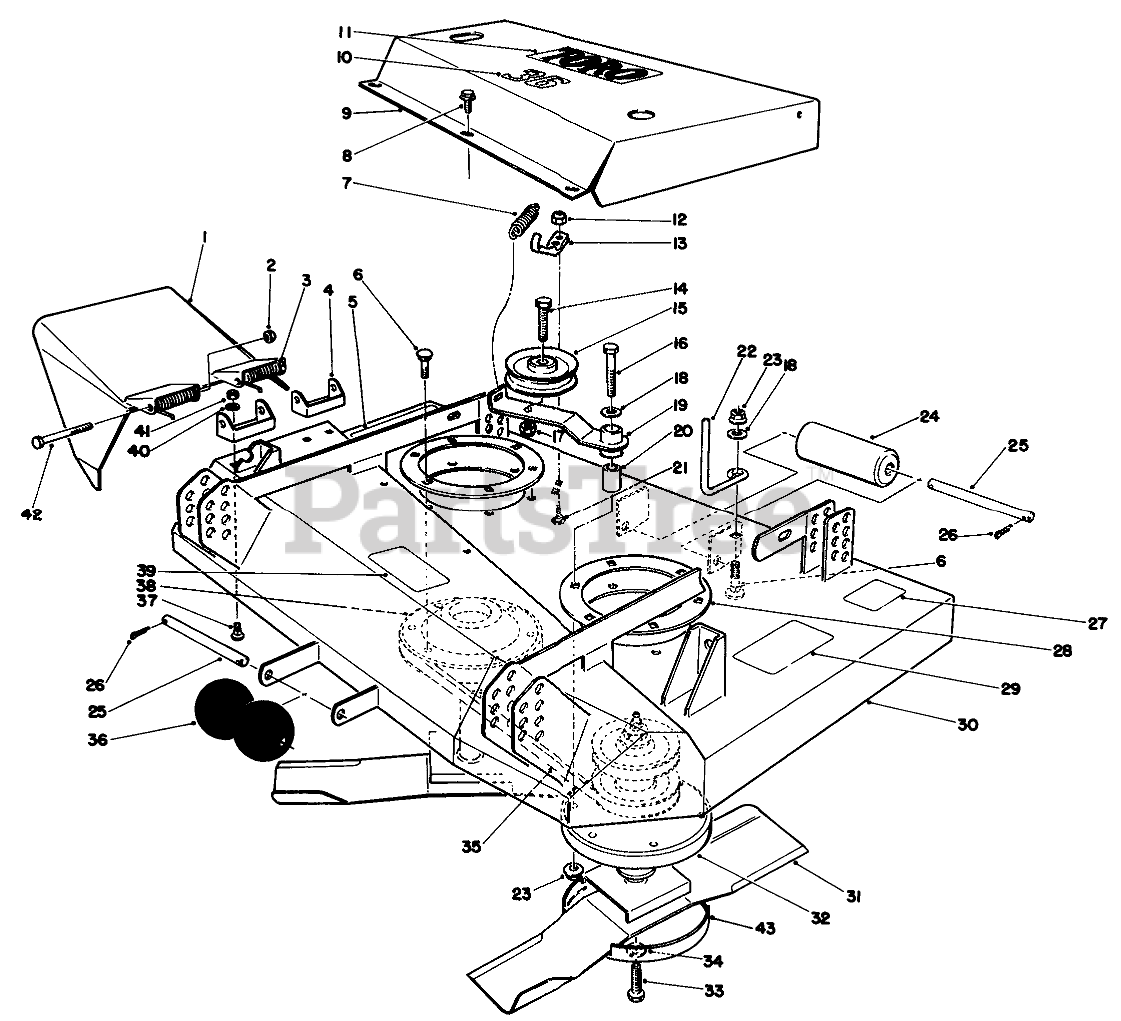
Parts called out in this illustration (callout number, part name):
1	Deflector-Grass
2	NUT-HEX
3	SPRING
4	Bracket-Pivot
5	DECAL-CAUTION, DEFLECTOR
6	SCREW-CARR
7	SPRING-EXTENSION
8	SCREW-HHFTF
9	COVER-DECK
10	Decal-36 Inch
11	Decal-Toro
12	NUT-LOCK, NI
13	ROD - SPRING
14	SCREW-HH
15	PULLEY-IDLER
16	SCREW-HH
17	NUT-HEX
18	WASHER-FLAT
19	Wa-Arm
20	SLEEVE-PIVOT, IDLER
21	SCREW-CARR
22	ROD-BELT
23	NUT-HF
24	ROLLER-DECK
25	SHAFT-ROLLER
26	PIN-COTTER
27	DECAL
28	SUPPORT-DECK, RING
29	DECAL-CAUTION, BLADE
30	Deck
31	BLADE-SAIL, EXTRA HIGH
32	HOUSING - SPINDLE ASM
33	SCREW-BLADE
34	WASHER-LOCK
35	V-BELT-DRIVE, DECK
36	ROLLER
37	SCREW-CARR
38	SPINDLE ASM
39	Decal-Caution
40	WASHER-LOCK
41	NUT-HEX
42	SCREW-HH
43	Cup-Scalp
